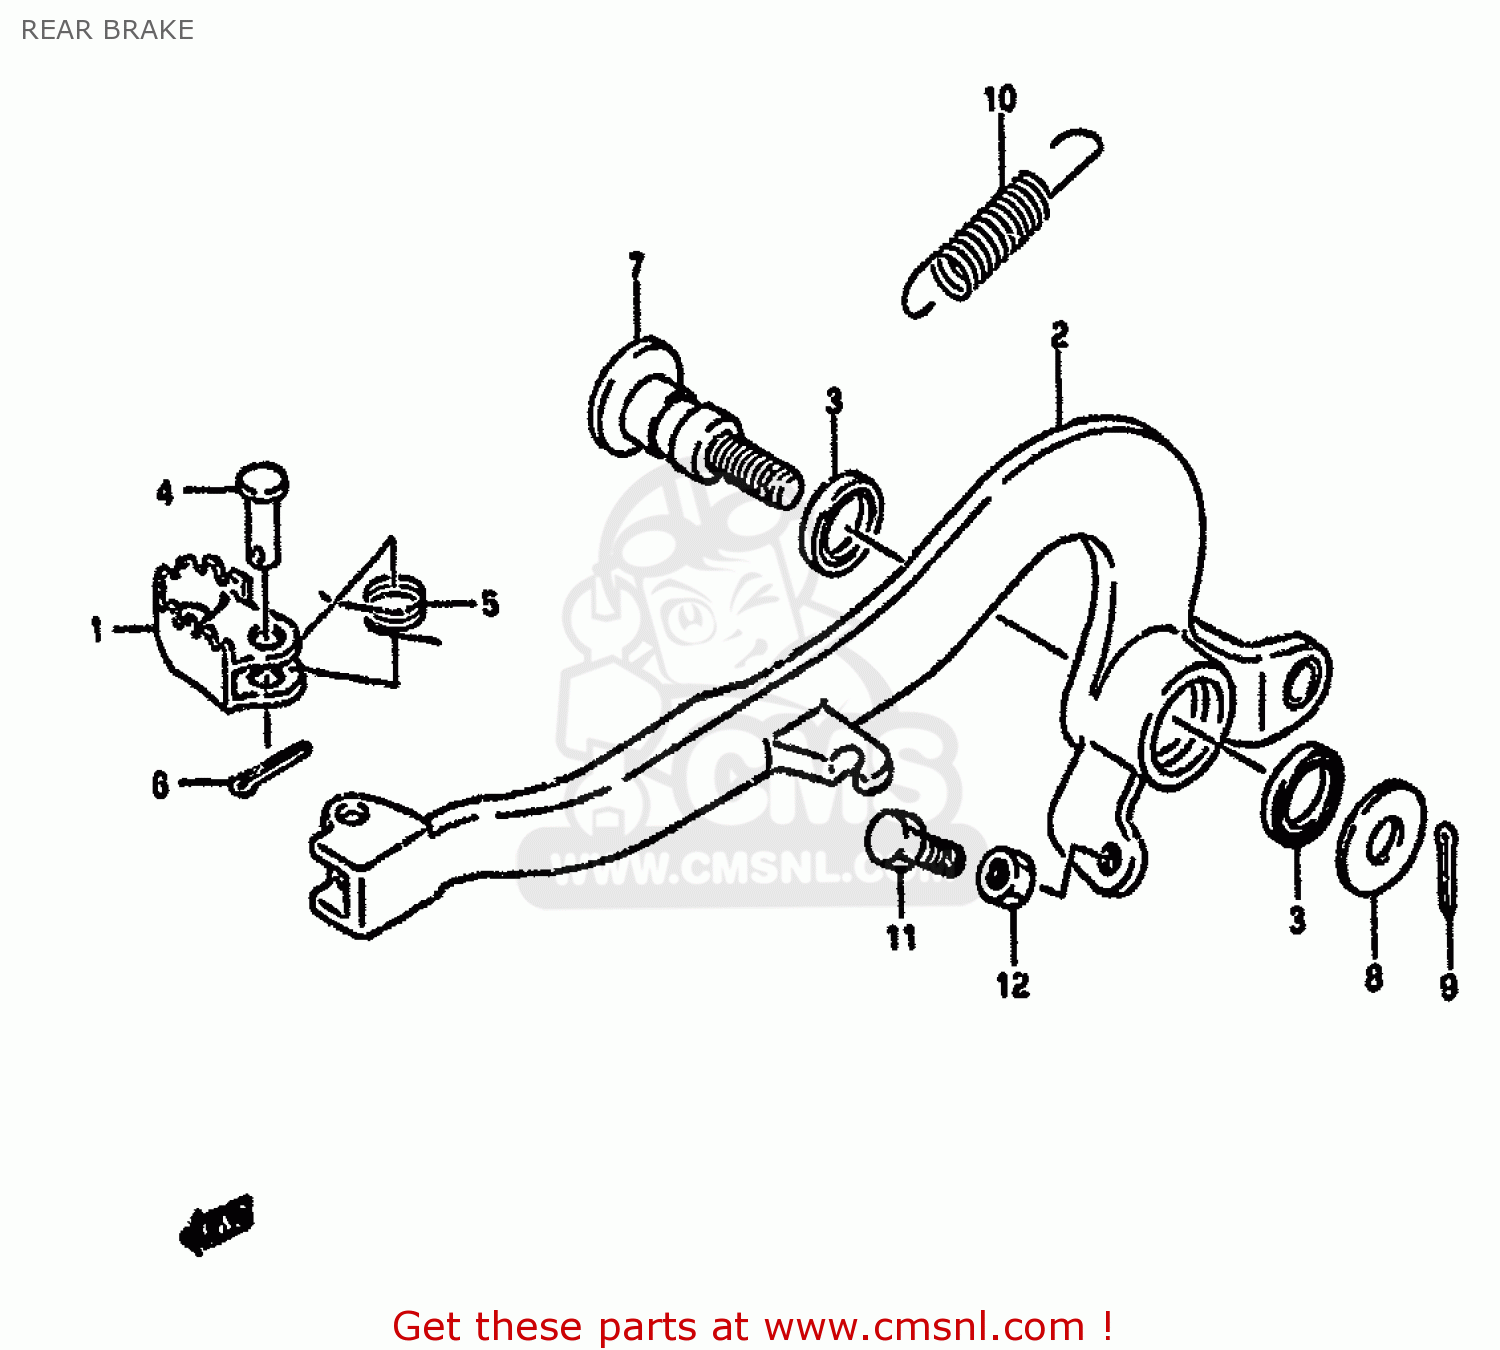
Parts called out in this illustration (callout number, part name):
1	PEDAL,BRAKE
2	ARM COMP,BRAKE PEDAL
3	SEAL,OIL(15X21X3)
4	PIN(6X23.5)
5	SPRING
6	PIN
7	SHAFT,BRAKE PEDAL
8	WASHER
9	PIN 20X20
10	SPRING
11	BOLT(6X23)
12	NUT
